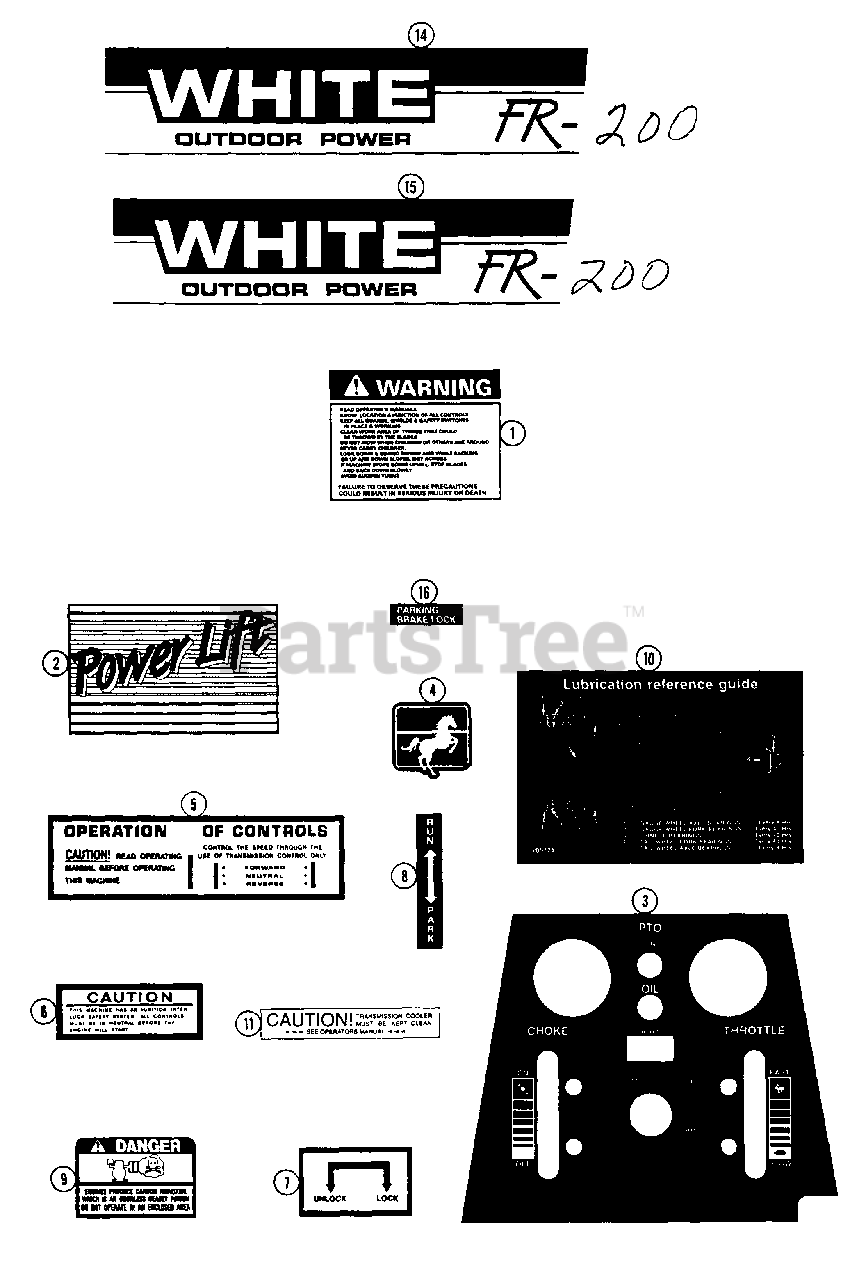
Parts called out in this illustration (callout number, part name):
1	DECAL - WARNING
2	DECAL - power lift
3	DECAL - instrument panel
4	MEDALLION - White "horse"
5	DECAL - operation
6	DECAL - caution interlock
7	DECAL - unlock/lock
8	DECAL - run/park
9	DECAL - danger carbon monoxide
10	DECAL - lubrication
11	DECAL - clean cooler
14	DECAL - body side R.H. "FR 200"
15	DECAL - body side L.H. "FR 200"
16	DECAL - brake lock
